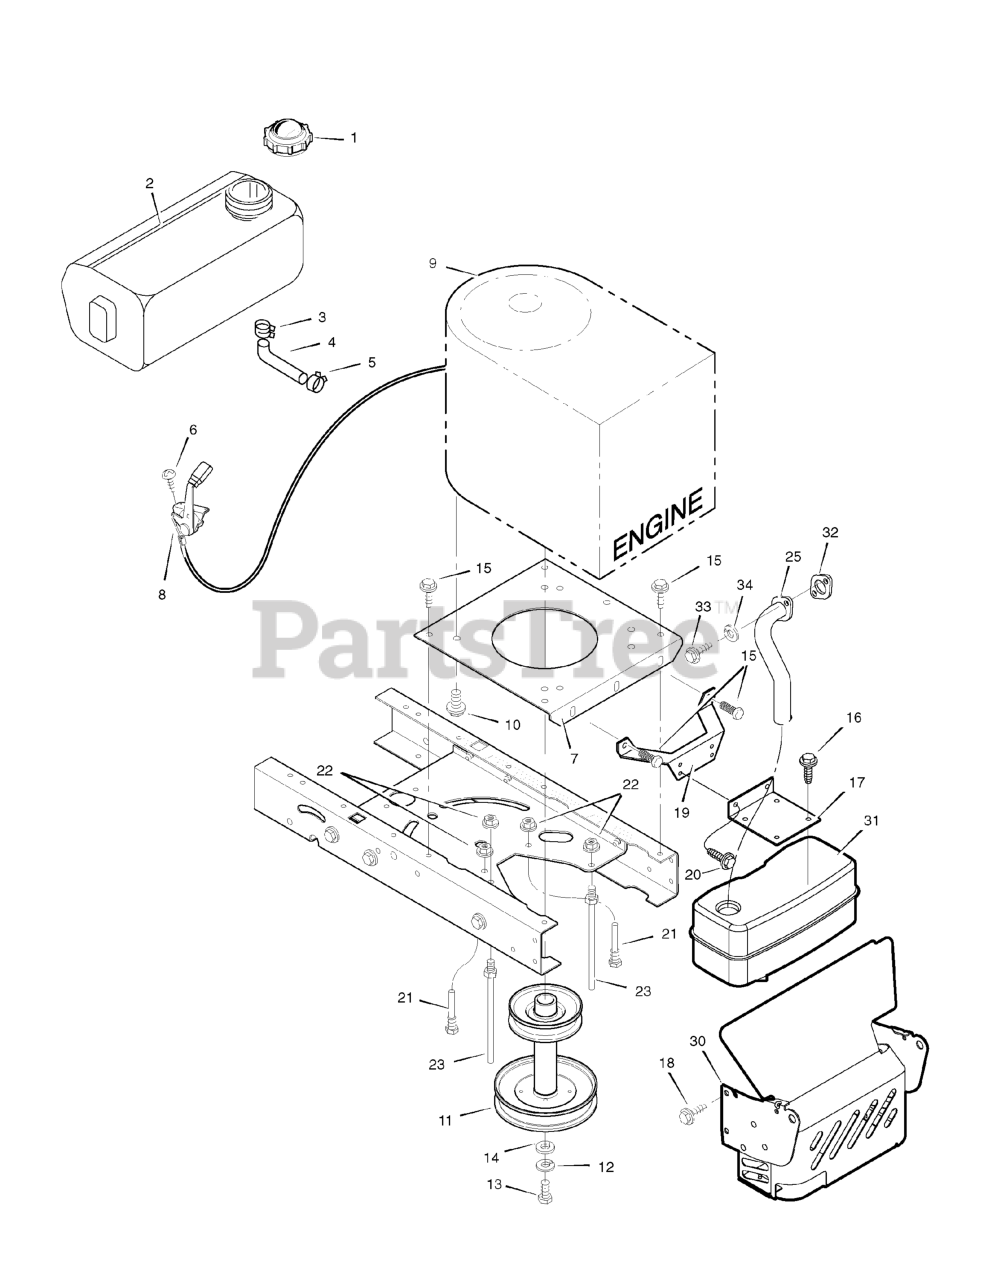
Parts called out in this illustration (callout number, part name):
1	Fuel Cap
2	Fuel Tank
3	Hose Clamp
4	Fuel Line (Must cut to length)
5	Hose Clamp
7	Plate, Engine
8	Throttle Control
9	Engine, BRIGGS & STRATTON *
10	Bolt, Engine Mount
11	STACK PULLEY ASSEMBLY
12	Lockwasher
13	Bolt, Hex
16	Bolt, Muffler
17	Bracket, Muffler
19	Bracket, Muffler Mount
21	Guide, Belt
22	Nut, Flange
23	Guide, Belt
25	Exhaust, Tube Single
30	Shield, Heat
31	Muffler
32	GASKET, Exhaust
33	Screw, Adapter
34	Washer, 31 .58 x .07 Split
